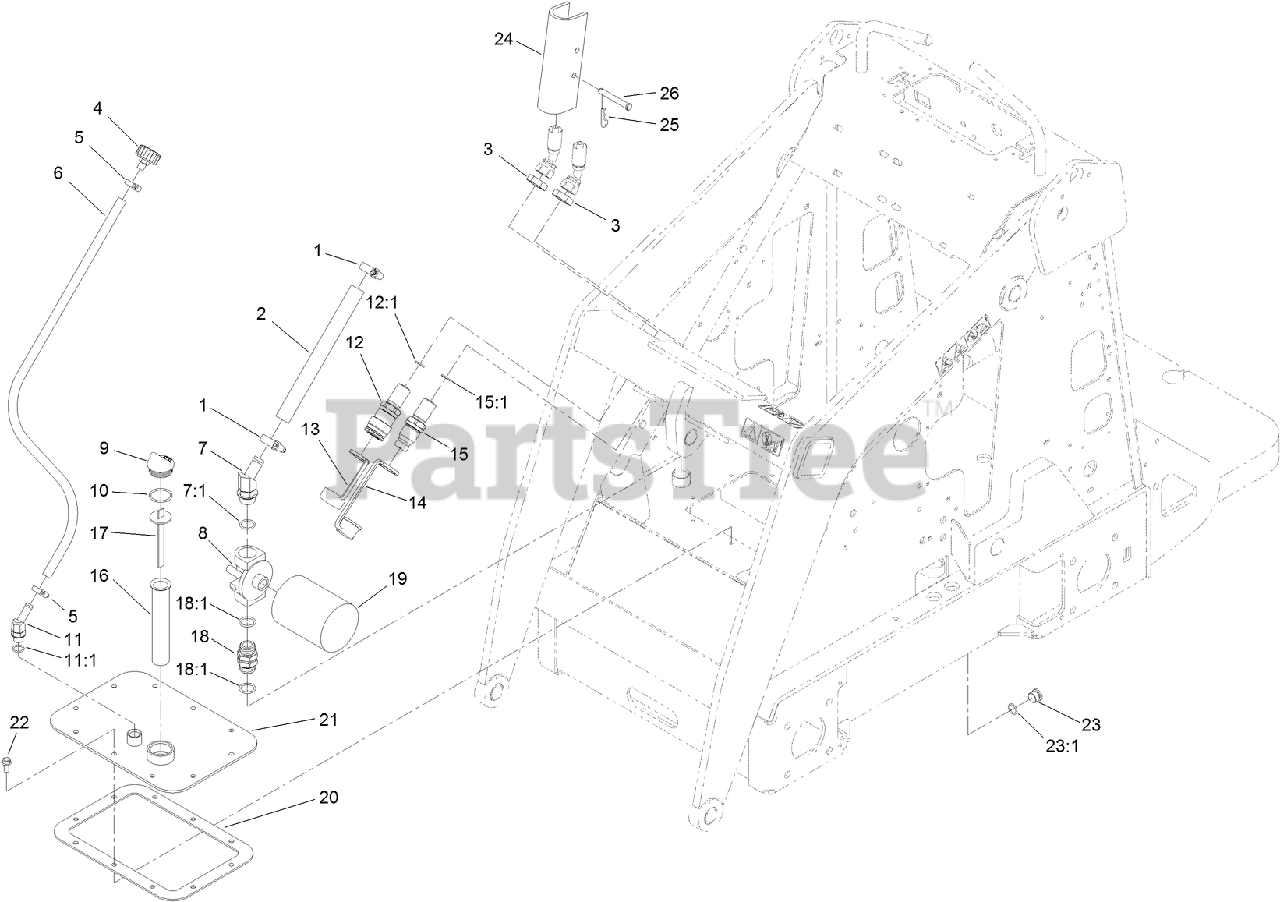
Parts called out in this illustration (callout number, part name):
1	CLAMP-HOSE
2	HOSE-HYD, SUCTION, HI
3	NUT-LOCK, BULKHEAD
4	BREATHER
5	CLAMP-HOSE
6	HOSE-VENT
7	FITTING-ELBOW45
7:1	O-RING
8	HEAD-FILTER
9	PLUG-PLASTIC
10	O-RING
11	FITTING-ELBOW, 45
11:1	O-RING
12	BULKHEAD COUPLER ASM
12:1	O-RING
13	CAP-DUST, COUPLER
14	CAP-DUST, NIPPLE
15	BULKHEAD NIPPLE ASM
15:1	O-RING
16	FILTER-SCREEN
17	DIPSTICK-OIL
18	FITTING-THREAD, STRAIGHT
18:1	O-RING
19	FILTER-OIL, TRANSMISSION
20	GASKET-COVER
22	SCREW-HHF
23	PLUG-HEX
23:1	O-RING
24	LOCK-CYLINDER
25	PIN-HAIR
26	PIN-CLEVIS
